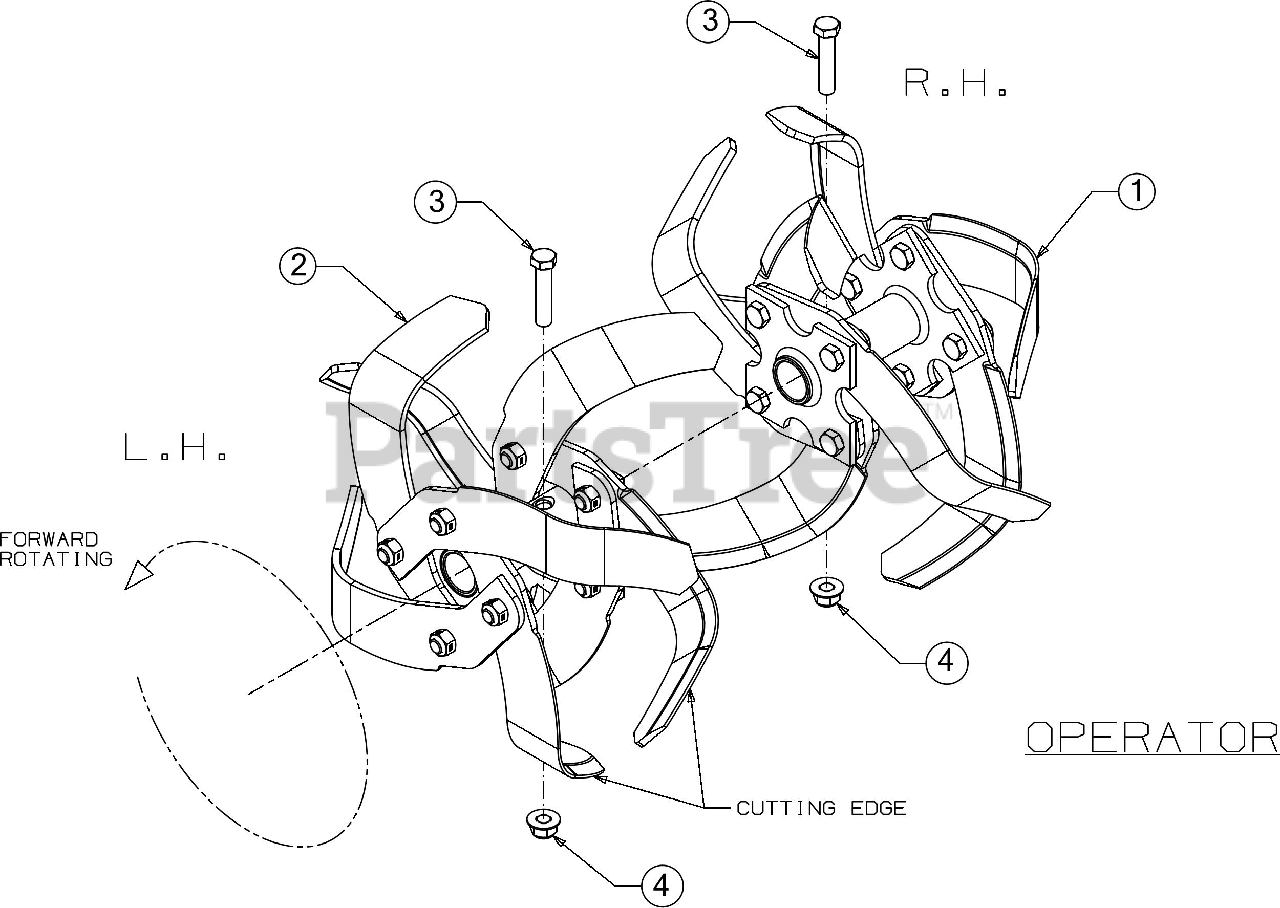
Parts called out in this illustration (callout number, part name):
1	SCREW 3/8-16 X 1 GR5
1	LOCK NUT 3/8-16
2	SCREW 3/8-16 X 1 GR5
2	LOCK NUT 3/8-16
3	HEX SCREW 3/8-16 X 1.75 GR5
